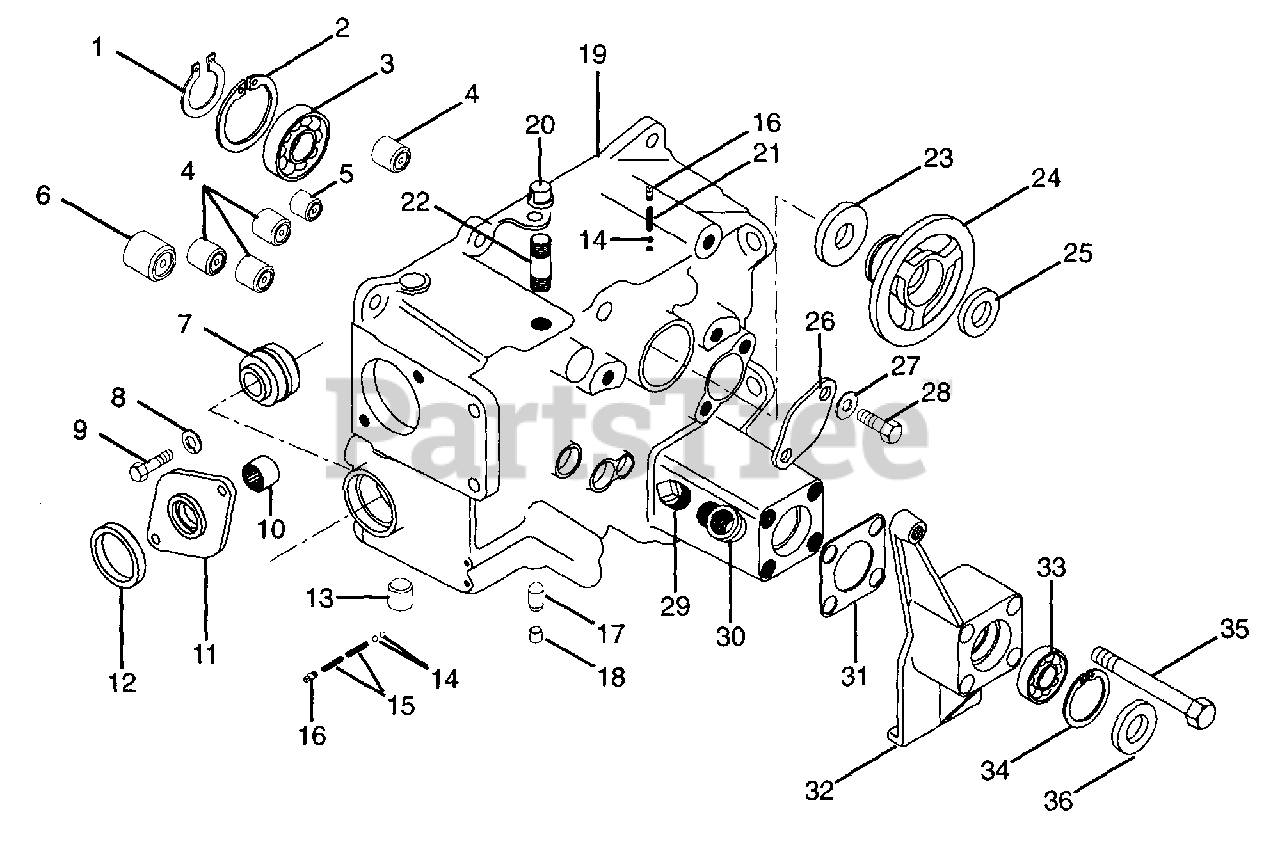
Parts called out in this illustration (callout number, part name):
1	Ring-Retaining-External 1.819 x .062
2	Ring-Retaining-Internal 3.52 x .109
3	Bearing-Ball 1.97 x 3.14 x .63
4	Bearing-Needle .75 x 1.0 x .75
5	Bearing-Needle .625 x .812 x .75
6	Bearing-Needle 1.0 x 1.25 x .75
7	Bearing-Assembly 1.000 x 1.980 x 1.243
8	Washer-Lock .313 x .078
9	Bolt-Hex .31-18 x 1.00 Grade 5
10	Bearing-Needle .75 x 1.000 x .50
11	Cap-Front PTO
12	Seal .750 x 1.250 x .136
13	Plug-Cup .500
14	Ball .312
15	Spring-Compression .045 x .30 x 1.50
16	Plug-Pipe .12
17	Pin-Interlock
18	Plug-Cup; 3/8
19	Assembly-Transmission Case
20	Cap-Pipe 1/2
21	Spring-Compression .045 x .300 x .938
22	Nipple-Pipe .50 x 2.50
23	Seal 2.250 x 3.002 x .375
24	Hub-Clutch
25	Seal .750 x 1.628 x .250
26	Plate-Cover
27	Washer-Flat-Steel .406 x .812 x .065
28	Bolt-Hex .38-16 x .75 Grade 5
29	Plug-Pipe .50
30	Elbow .50 x 90
31	Gasket
32	Retainer-Axle Bearing
33	Bearing-Ball 1.25 x 2.25 x .50
34	Ring-Retaining-External 2.49 x .078
35	Bolt-Hex .50-13 x 3.25 Grade 5
36	Seal 1.250 x 2.250 x .500
